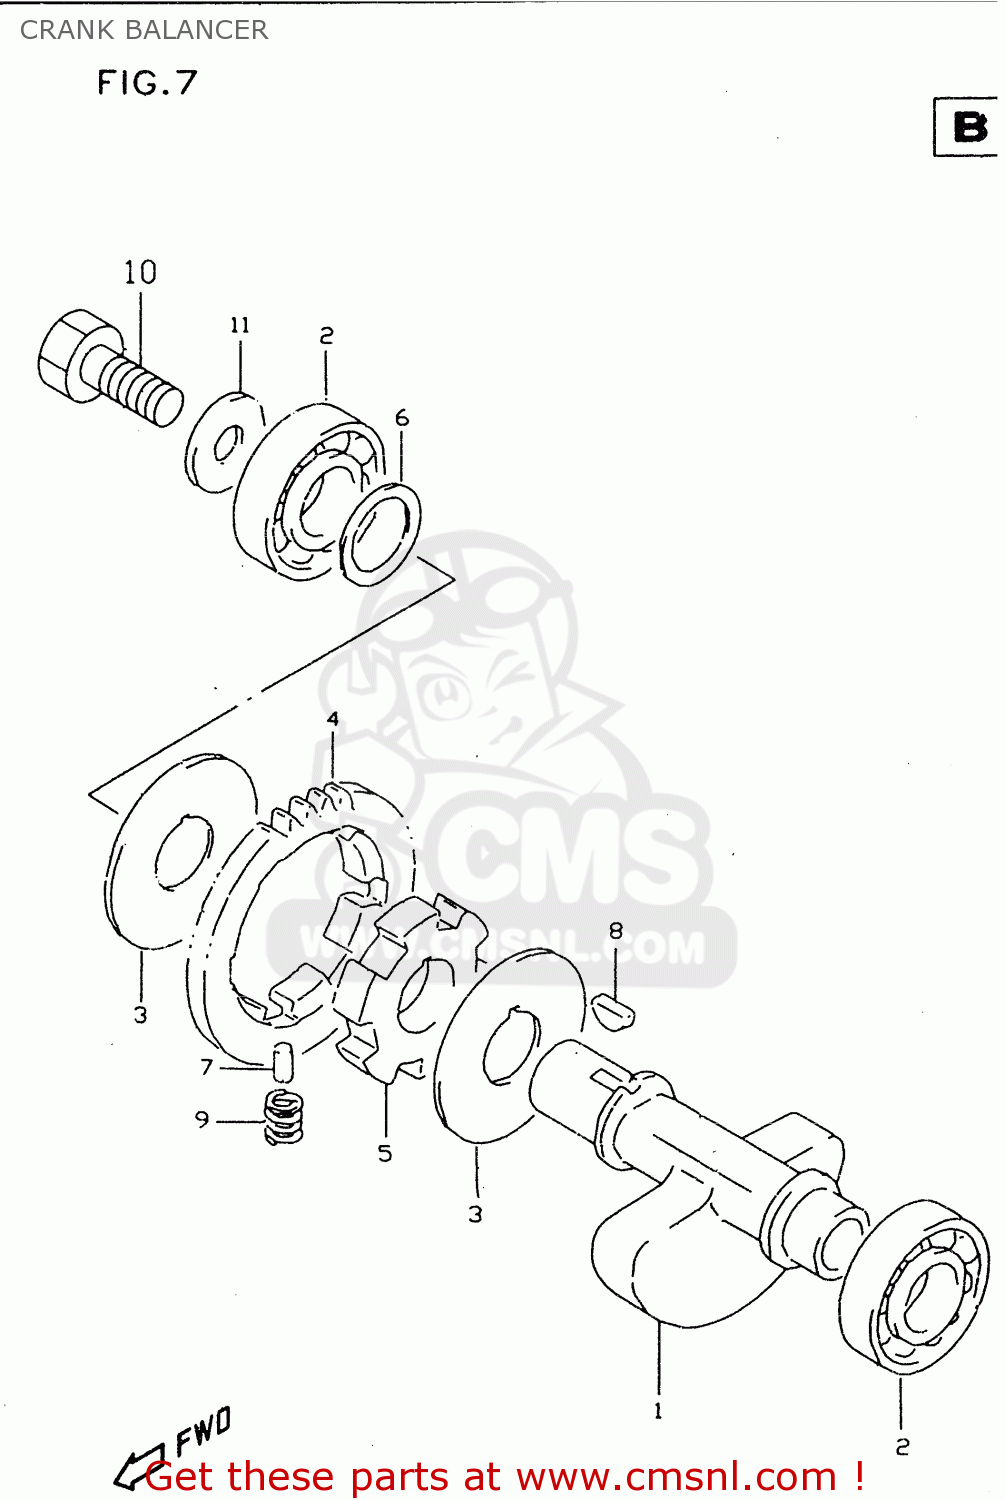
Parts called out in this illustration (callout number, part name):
1	SHAFT,CRANK BALANCER
2	BEARING(20X47X14)
3	WASHER
4	GEAR,CRANK BAL DRIVEN(NT:37)
5	RACE,CRK BAL DRIVEN GEAR INNER
6	THRUST WASHER
7	PIN(4.5X9.5)
8	KEY
9	SPRING
10	BOLT
11	WASHER
